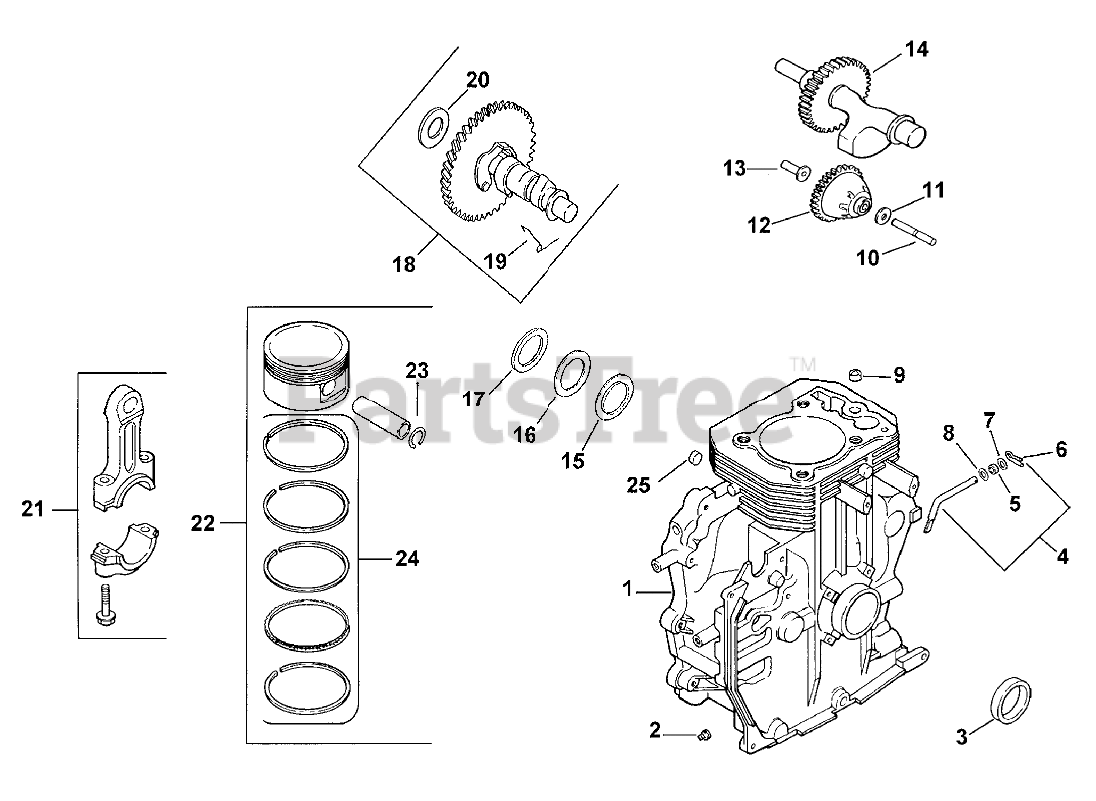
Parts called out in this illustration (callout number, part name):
1	Short Block
2	Plug
3	Seal-Crankshaft
4	Kit, governor cross shaft (Includes # 6)
5	Seal-Cross Shaft
6	Clip-Hitch Pin
7	Washer
8	Washer, plain 6 mm
9	Dowel-Locating
10	Shaft-Gear, Governor
11	Washer
12	Gear, governor
13	Pin-Governor
14	Shaft, balance
15	Bearing, thrust
16	Washer, thrust
17	Shim, thrust
18	Kit, camshaft (Includes
19	Spring-Actuating
20	Shim-Camshaft
21	Rod Connecting STD
22	Piston w/Ring Set (Std.) (Includes 23,24)
23	Retainer-Piston Pin
24	Ring Set STD
25	Plug
